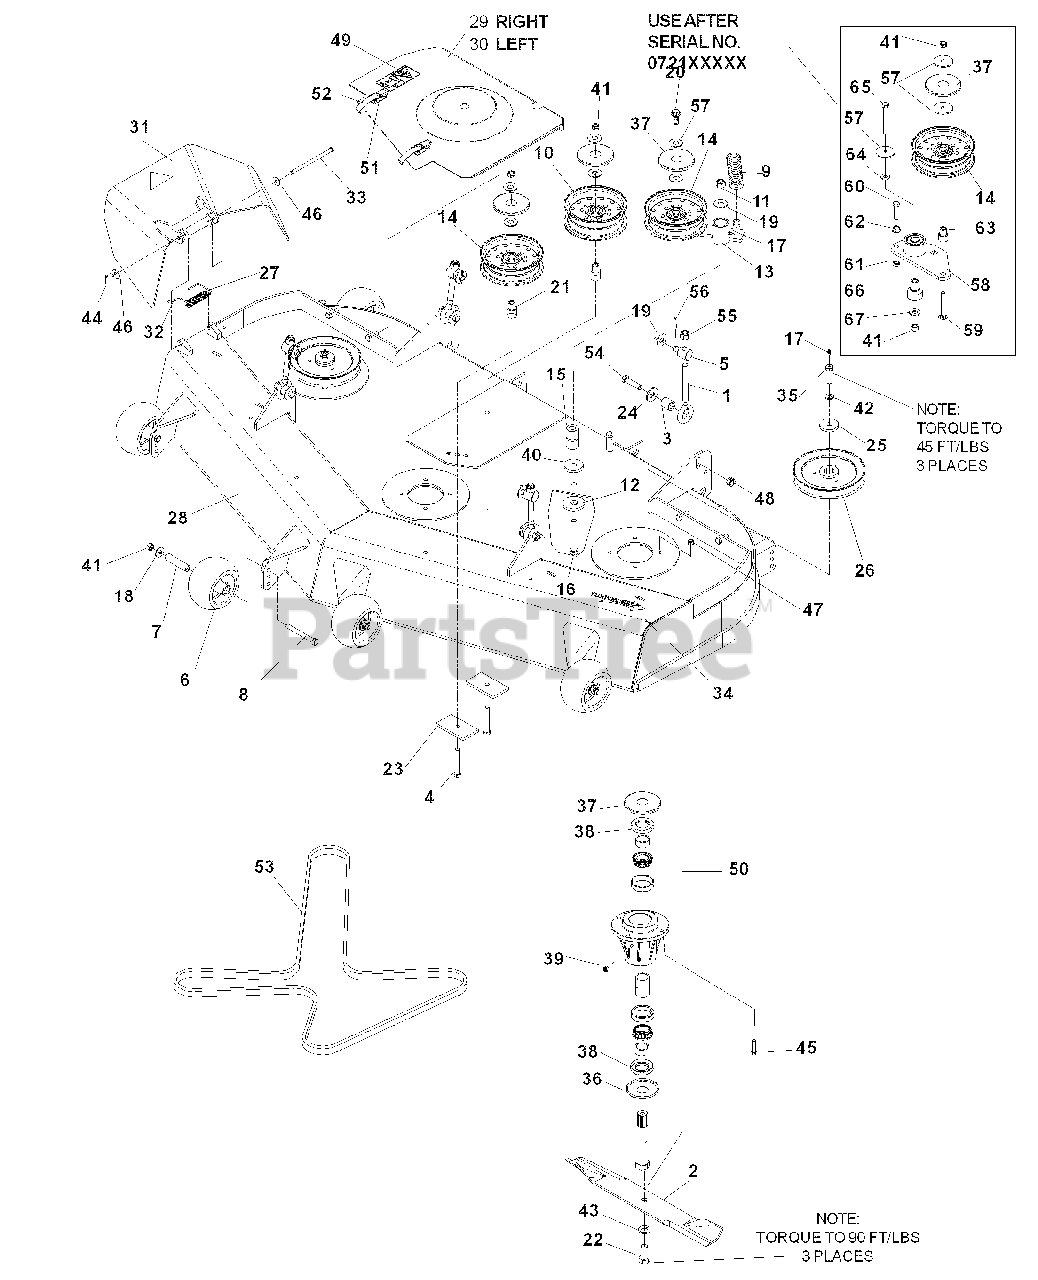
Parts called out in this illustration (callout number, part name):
2	BLADE, 21"
4	HCS, 3/8 -16 x 2 3/4
6	ROLLER, ANTI SCALP
8	HCS, 3/8 -16 x 3 1/2, GR8
9	SPRING, EXTENSION
10	PULLEY, IDLER
11	NUT, 1/2-13, NYLOC
12	WASHER, .65
14	PULLEY, IDLER
15	BUSHING, PIVOT
16	HCS, 1/2 -13 x 3 1/4
17	ZERK, STRAIGHT, 1/4 -28
18	WASHER, 3/8
19	WASHER, 9/16
20	HCS, 3/8 -16 x 1
21	BUSHING, IDLER
22	HCS, 5/8 -18 x 1 1/4
23	PAD
24	SPRING WASHER, 1/2
25	WASHER, .469
26	PULLEY
27	CAP-SLEEVE
28	DECK W/DECALS
29	BELT SHIELD, RIGHT
30	BELT SHIELD, LEFT
31	DISCHARGE CHUTE
32	SPRING, TORSION
33	PIN-CLEVIS, 5/16 DIA. x 5.19
34	DECAL, TUNNEL RAM
35	HCS, 7/16 -20 x 1 1/2, GR8,SPEC
36	BOTTOM DUST CAP
37	TOP DUST CAP
38	SHAFT SEAL
39	PLUG, VENTED
40	WASHER, 1/2
41	NUT, 3/8 -16, NYLOC
42	LOCKWASHER, 7/16
43	LOCKWASHER, 5/8
44	PIN COTTER, 1/8 x 3/4
45	HCS, 5/16 -18 x 1 1/4
46	WASHER, 5/16
47	NUT, 5/16 -18, NYLOC
48	NUT, 7/16 -14, CNTRLCK,GR A
49	DECAL, EURO SEVERING
50	SPINDLE ASSEMBLY
52	DRAW LATCH
54	HCS, 7/16 -14 x 1 3/4
55	NUT, 1/2 -13, NYLOC
56	PIN COTTER, 1/8 x 1
57	WASHER, 3/8, SPEC
58	ARM, IDLER, W/BEARINGS
59	RHSNB, 3/8-16 x 2 3/4,
60	HCS, 3/8-16 x 1 1/2, GR8
61	NUT, 3/8-16, JAM
62	NUT, 3/8-16, WHIZLK
63	BUSHING, IDLER
64	WASHER, 3/8, SAE
65	HCS, 3/8-16 x 3
66	PIVOT, BEARING
67	WASHER, 3/8
